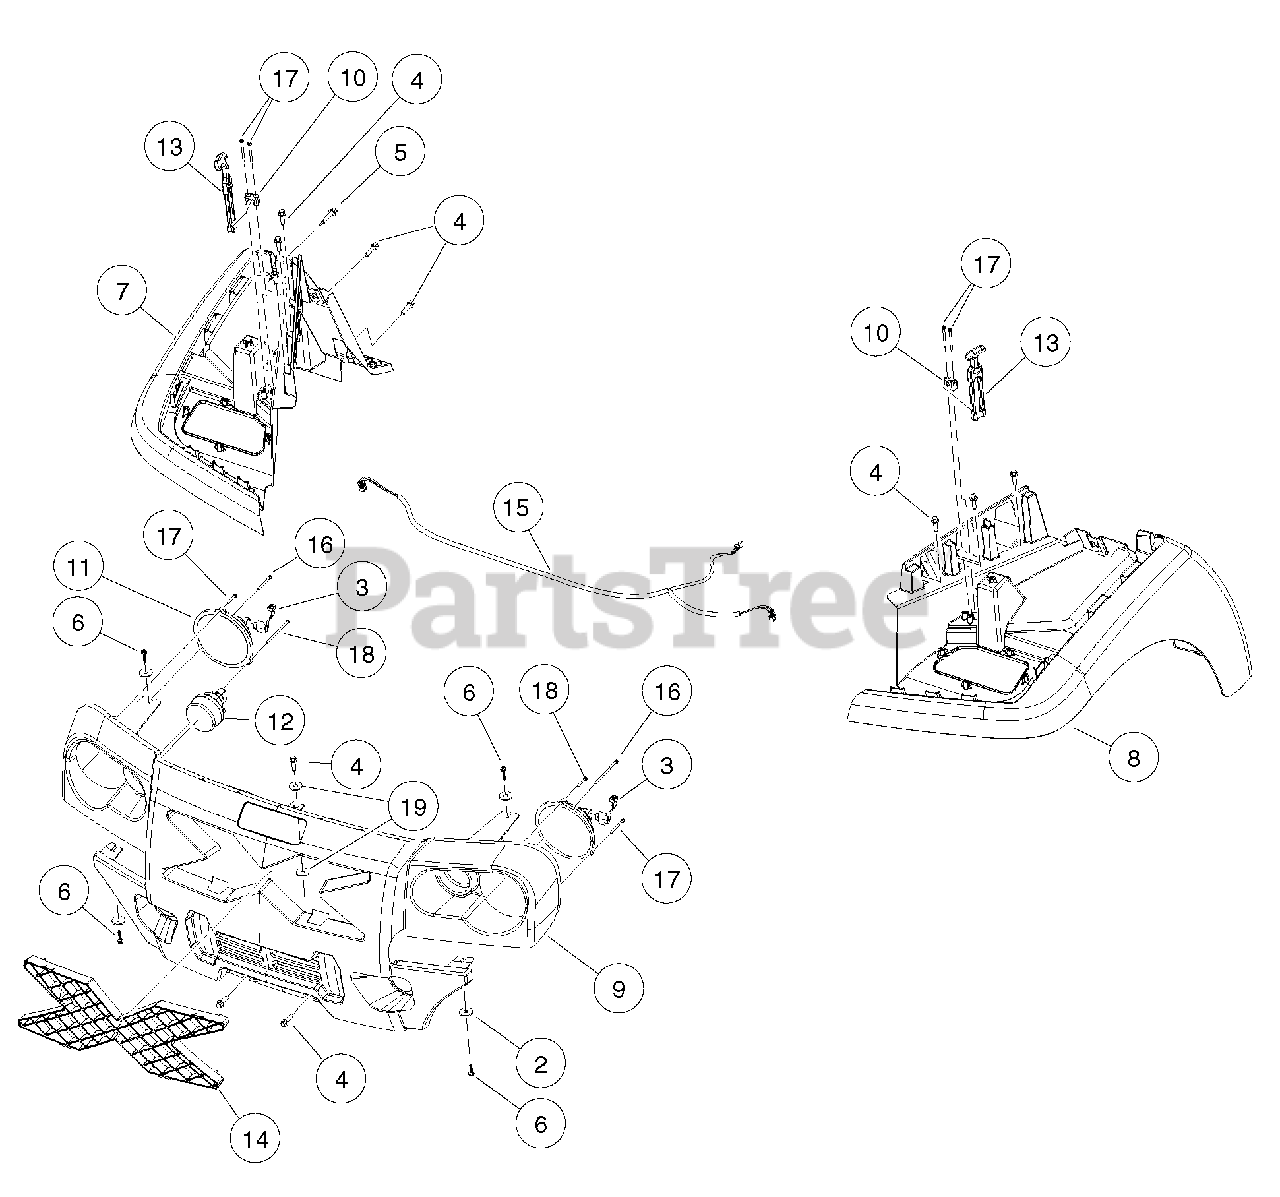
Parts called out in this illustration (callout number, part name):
1	Instl, Fascia, Fenders, XRT
2	Washer, 5/16 Type B Flat
3	Connector Harness Assembly, Headlight
4	Screw, M8X1.25X30, Hex
5	Screw-1/4-20x56 Hwh Self Drill
6	Screw,m6,torx,interlock,thread
7	Fender, Front, Pass, AWD
8	Fender, Front, Drv, AWD
9	Fascia, Front, XRT, AWD
10	Bracket, Latch, Draw
11	Headlight, 6 In Round
12	Light, Turn Signal, 3 In Round
13	Latch, Draw, Hood
14	Grill, XRT
15	Harness, XRT/CA Restyle HDL
16	Screw, #8x1.25 Ab Thd, Hex Hd
17	Screw, #8x2.00 AB Thd, Hex Hd
18	Screw, #8x3.50 Ab Thd, Hex Hd
19	Washer, 3/8 Type B Flat
